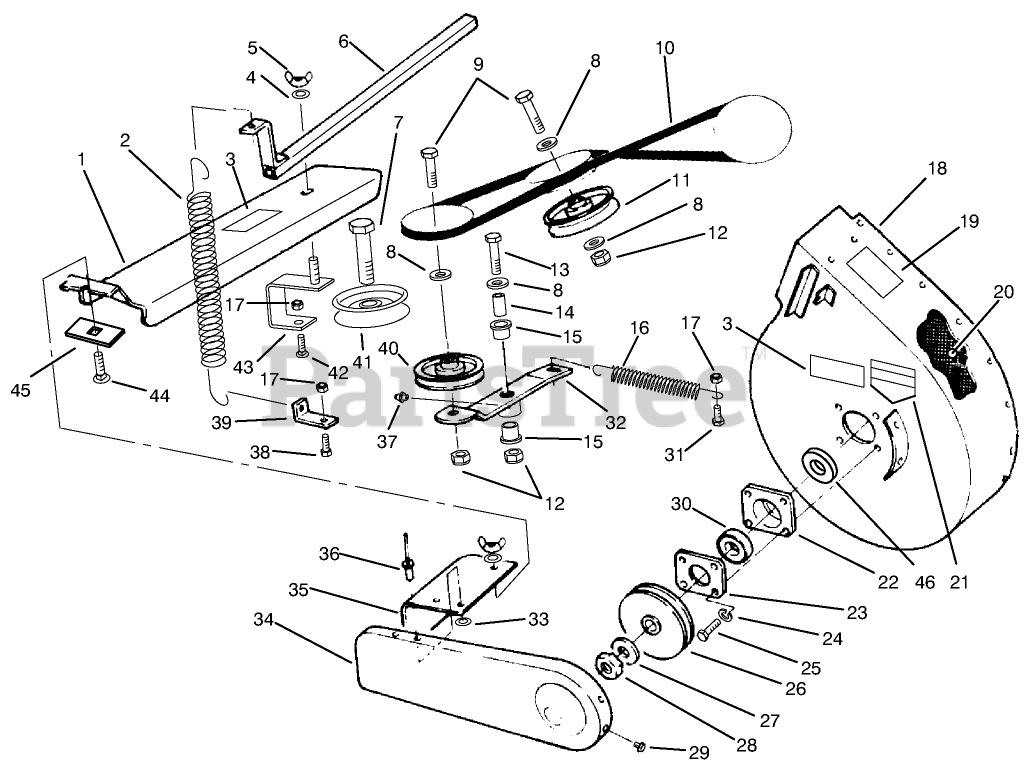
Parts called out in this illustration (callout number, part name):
1	LATCH-BAGGER TOP B
2	SPRING-EXTENSION
3	DECAL-DANGER
4	WASHER-PLAIN
5	NUT-WING, LOCK
6	SUPPORT-WELDED B
7	SCREW-HH
8	WASHER-FLAT
9	SCREW-HH
10	V-BELT
11	PULLEY-IDLER
12	NUT-LOCK, NI
13	SCREW-HH
14	SPACER
15	BUSHING
16	SPRING - EXTENSION
17	NUT-LOCK, NI
18	Blower
19	DECAL-DANGER
20	STRIP-WEAR
21	DECAL-DANGER
22	CUP-BEARING
23	Cover-Plate
24	WASHER-LOCK
25	SCREW-HH
26	PULLEY-BLOWER R
27	WASHER-FLAT
28	NUT 5/8-11 L.H.
29	SCREW
30	BEARING-BALL
31	SCREW-HH
32	ARM-IDLER-WELDED B
33	WASHER-FLAT
34	SHIELD-PULLEY B
35	SHIELD
36	RIVET-BLIND
37	FITTING-GREASE
38	SCREW-HH
39	BRACKET-ANGLE B
40	PULLEY-IDLER, FLAT
41	PULLEY
42	BOLT-CARR
43	Bracket
44	SCREW-CARR
45	STRAP B
46	SPACER-BEARING
